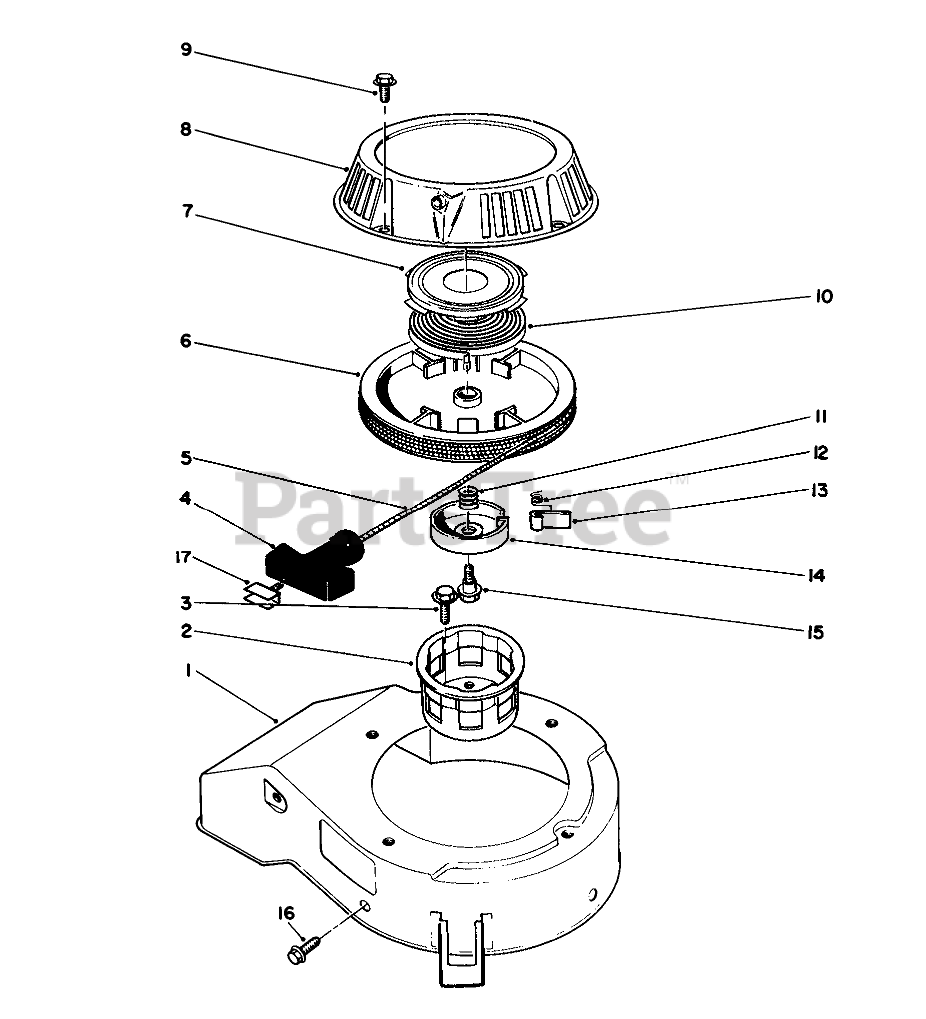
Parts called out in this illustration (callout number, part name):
1	COVER
2	CUP - STARTER
4	HANDLE-RECOIL
5	ROPE-STARTER
7	Retainer Cup-Recoil Spring
9	SCREW-HHF
10	Spring-Recoil
11	SPRING
12	SPRING
14	RETAINER
17	Insert Handle
